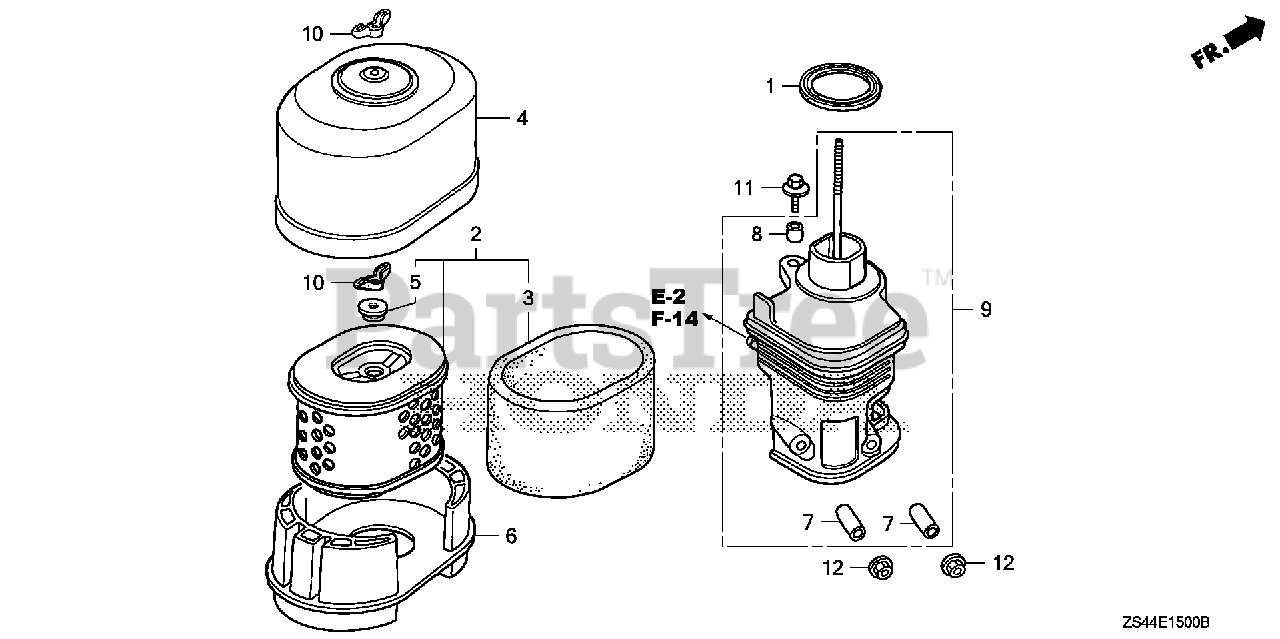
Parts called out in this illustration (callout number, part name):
1	GASKET, ELBOW
2	ELEMENT, AIR CLEANER (DUAL)
3	FILTER (OUTER)
4	COVER, AIR CLEANER (DUAL)
5	GROMMET, AIR CLEANER
6	NOSE, MUFFLER
7	COLLAR, AIR CLEANER
8	COLLAR B, AIR CLEANER
9	ELBOW, AIR CLEANER
9	ELBOW COMP, AIR/C
10	NUT, TOOL BOX SETTING
11	BOLT-WASHER (6X22)
12	NUT, FLANGE (6MM)
